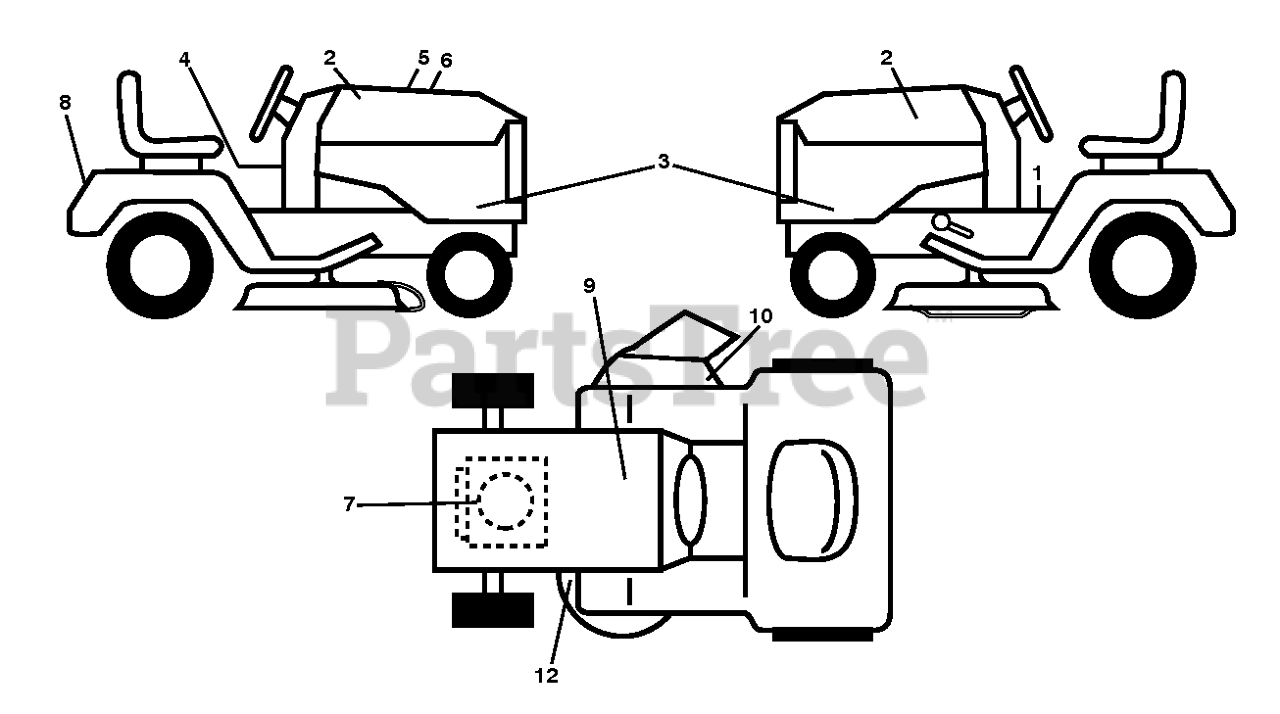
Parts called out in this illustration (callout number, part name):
1	DECAL.WARN.START.INSTRUCTIONS
2	DECAL.BADGE.170MM.TEXTLOGO.
3	DECAL.SIDE.PANEL.YTH22V46.2013
4	DECAL, WARNING SPARK ARRESTOR
5	DECAL.WARNING.CUST.RESP.E85.
7	DECAL.ENG.BS.22HP.INTK
8	DECAL.FENDER
9	DECAL BTRY SYMBOLS
10	DECAL.WARN.KEEP.HAND.AWAY
12	DECAL V BELT SCHEMATIC
